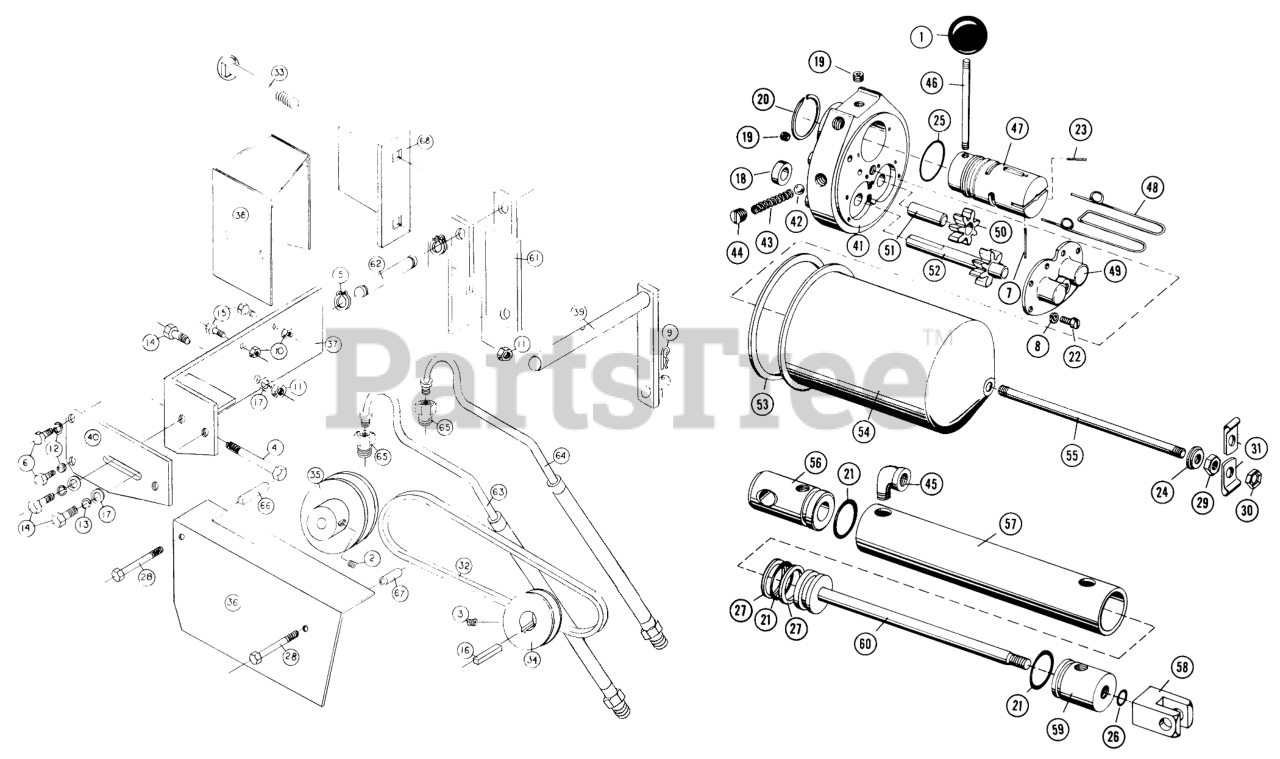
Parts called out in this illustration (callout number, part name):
1	Knob
2	Snap Ring
3	Set Screw 1/4-20 x 1
4	Cap Screw, 3/8 x 2 1/2
5	Snap Ring
6	Hex Rd. Cap Screw 5/16-18 x 5/8
7	1/8 x 1 1/4 Roll Pin
8	Lock Washer #10-32
9	Hair Pin Cotter
10	1/4-20 Lock Nut
11	Nut
12	Lock Washer 5/16
13	Lockwasher 3/8
14	Bolts 3/8-16 x 3/4
15	1/4-20 x 5/8 Hex Hd. Cap Screw
16	Key 1/4 x 1/4 x 1
17	3/8 Washer
18	Seal
19	Allen Hd. Pipe Plug 1/8
20	Snap Ring
21	O Ring
22	Cover Screw #10-32 x 7/16
23	Roll Pin 5/32 x 5/8
24	Washer
25	O Ring
26	O Ring
27	Back Up Washer
28	Hex Hd. Cap Screw 5/16-18 x 2 3/4
29	Hex Jam Nut 3/8-16
30	Hex Pal Nut 3/8-16
31	Tube Clamp 1/4 I.D.
32	"V" Belt 3L-510
33	Carriage Bolt
34	Pulley 2 1/4 Dia.
35	Pulley
36	Belt Guard
37	Pump Mounting Bracket
38	Instrument Mounting Bracket
39	Lift Link
40	Spacer
41	60-950-01 GIL 6HP 2
42	Ball
43	Spring
44	Plug
45	Street Elbow 1/4 NPTF
46	Handle
47	Spool Valve
48	Spring
49	Cover
50	Gear
51	Shaft
52	Drive Shaft Ass-y.
53	Gasket
54	Reservoir
55	Stud
56	Head
57	Tube
58	Clevis
59	Guide
60	Piston Rod Ass-y.
61	Cylinder Support
62	Pin
63	Hose
64	Hose
65	Tube Coupling
66	Pipe Spacer 1/4 x 2 1/8 lg
67	Washer-Seal
68	Link-Mtg. Bracket
